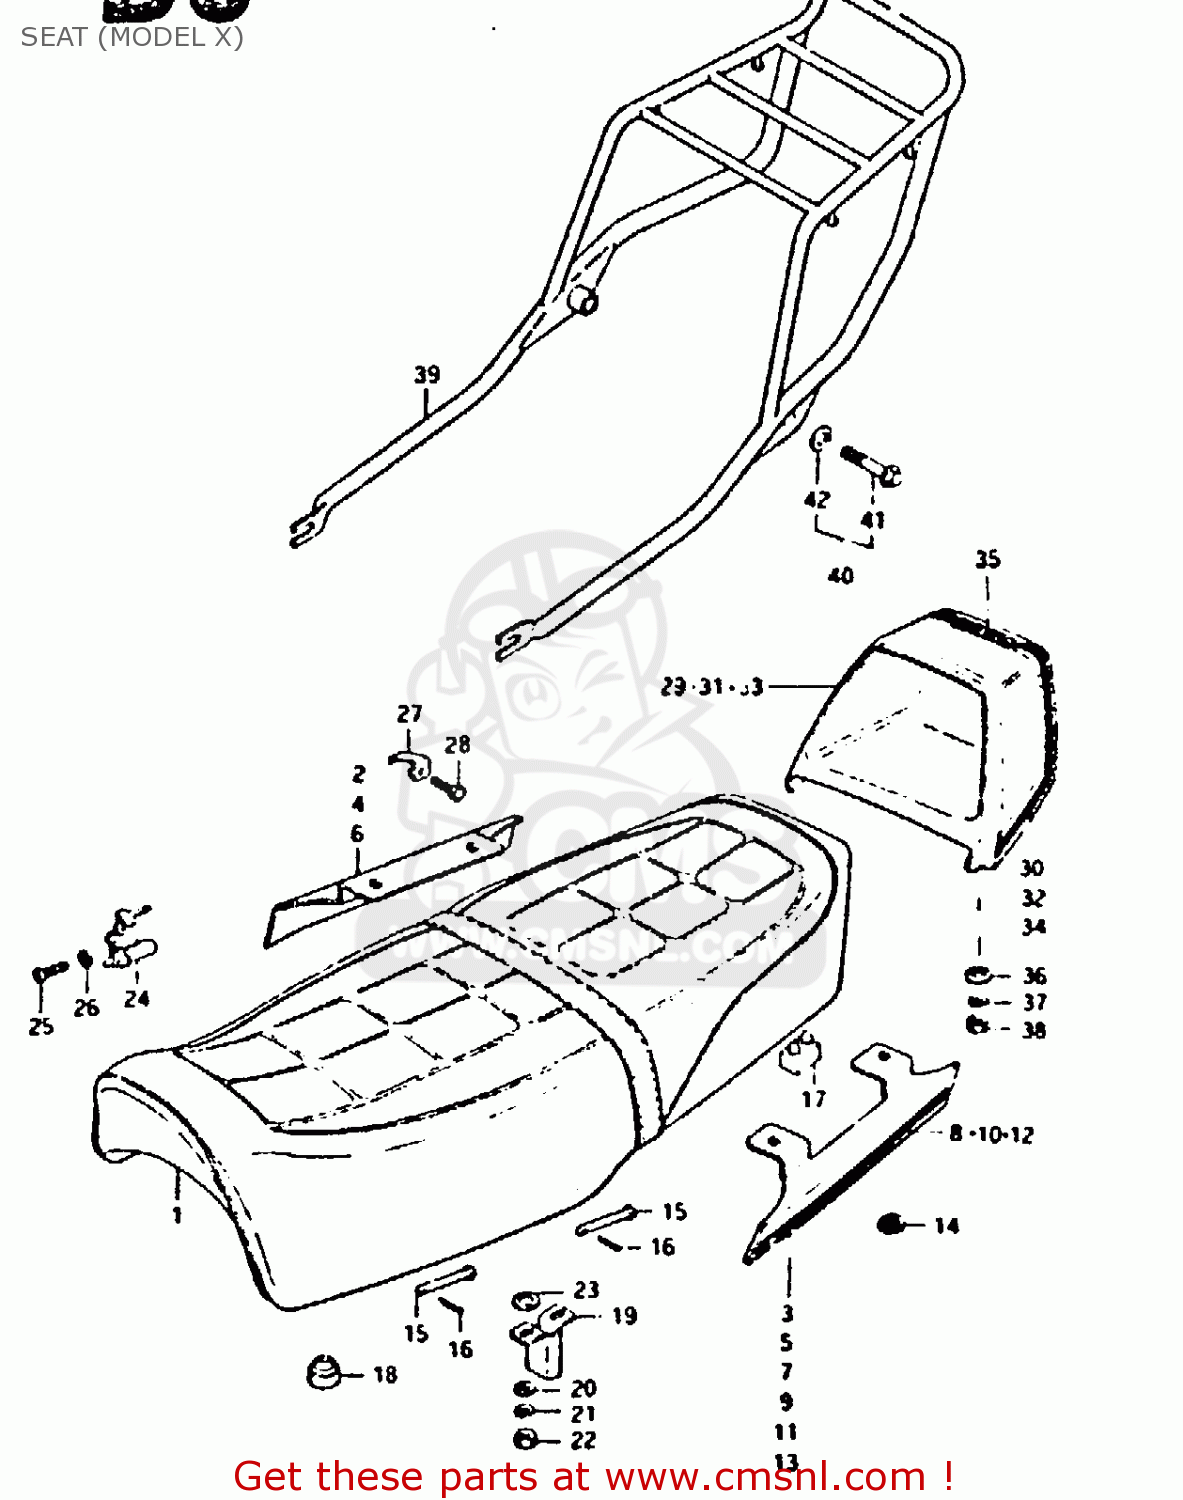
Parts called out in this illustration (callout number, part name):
1	SEAT (BLACK)
2	MOULDING, RH (BLUE)
3	TAPE, RH
4	MOULDING, RH (BLACK)
5	TAPE, RH
6	MOULDING, RH (RED)
7	TAPE, RH
8	MOULDING, LH (BLUE)
9	TAPE, LH
10	MOULDING, LH (BLACK)
11	TAPE, LH
12	MOULDING, LH (RED)
13	TAPE, LH
14	NUT
15	PIN
16	PIN
17	CUSHION
18	CUSHION
19	STRIKER,SEAT LOCK
20	WASHER
21	LOCK WASHER
22	NUT 6MM
23	WASHER(6.5X18X1)
24	LOCK ASSY,SEAT
25	SCREW
26	LOCK WASHER
27	SPRING,HELMET HOLDER
28	BOLT 5X16
29	COVER, SEAT TAIL (BLUE)
30	TAPE SET
31	COVER, SEAT TAIL (BLACK)
32	TAPE SET
33	COVER, SEAT TAIL (WHITE)
34	TAPE SET
35	EMBLEM,SEAT TAIL COVER
36	WASHER
37	LOCK WASHER
38	NUT 6MM
39	CARRIER, SPORTS
40	BOLT SET, CARRIER
41	BOLT
42	WASHER(10.3X25X1.5
